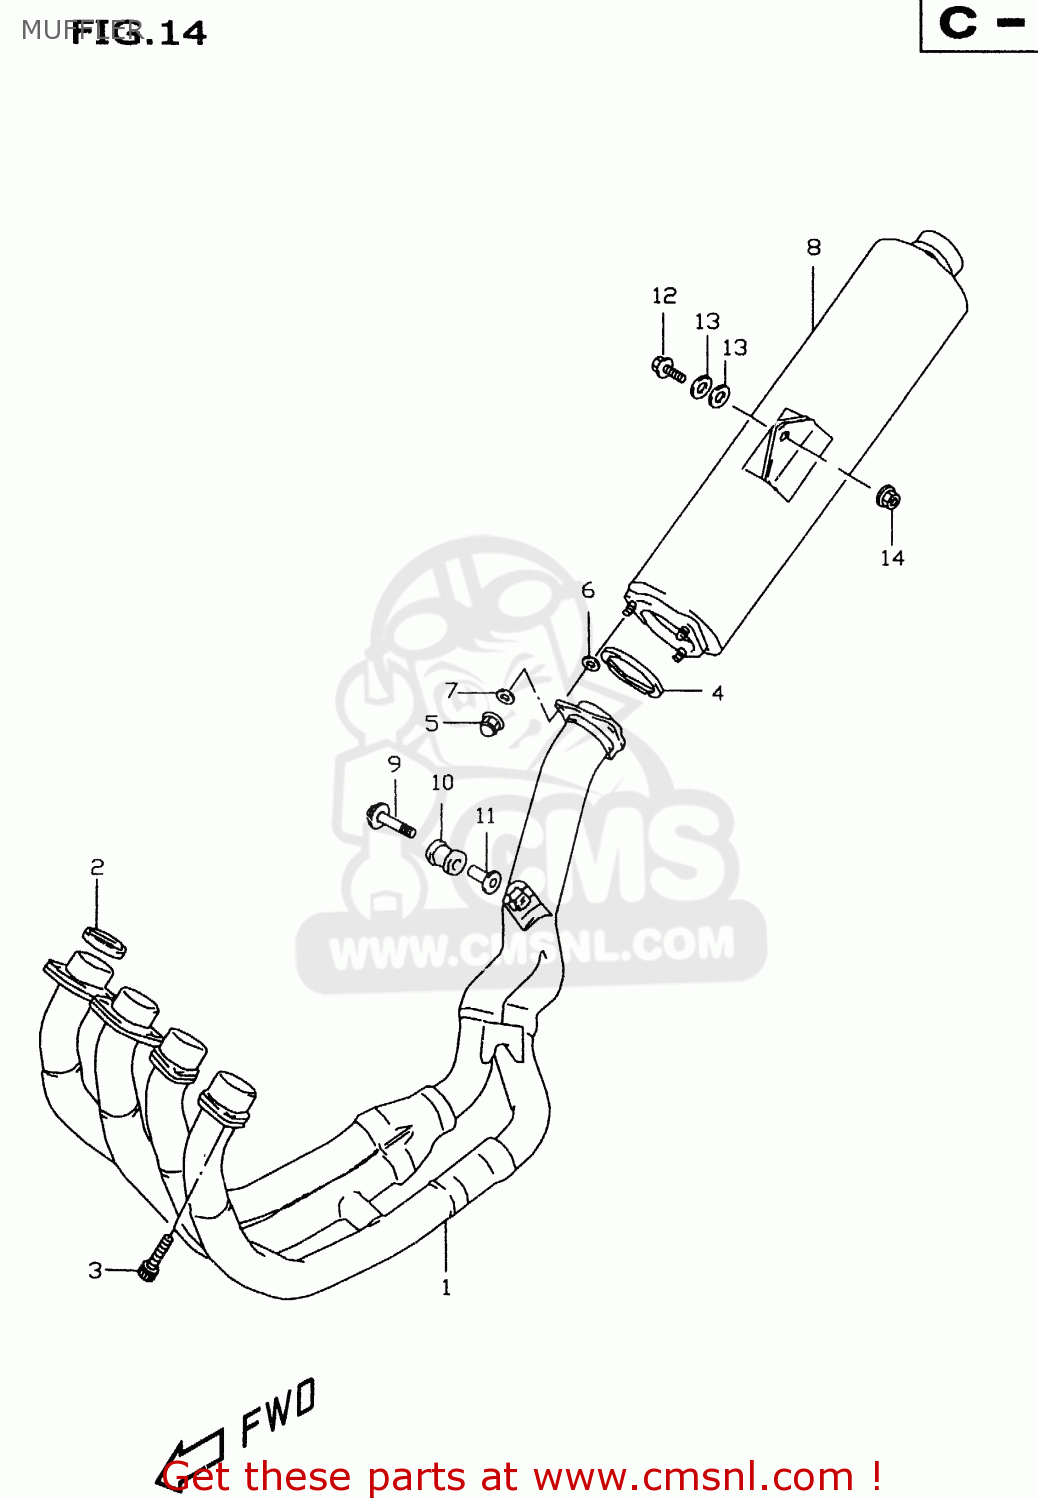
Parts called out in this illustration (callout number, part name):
1	EXHAUST
2	GASKET,EXHAUST PIPE
3	BOLT
4	GASKET,MUFFLER JOINT
5	NUT
6	WASHER(8.5X18X1.6)
7	O RING(D:1.9,ID:7.8)
8	BODY,MUFFLER
9	BOLT 8X45
10	CUSHION
11	SPACER(8.6X12X24.2)
12	BOLT
13	WASHER (8.2X24X1.6)
14	NUT
